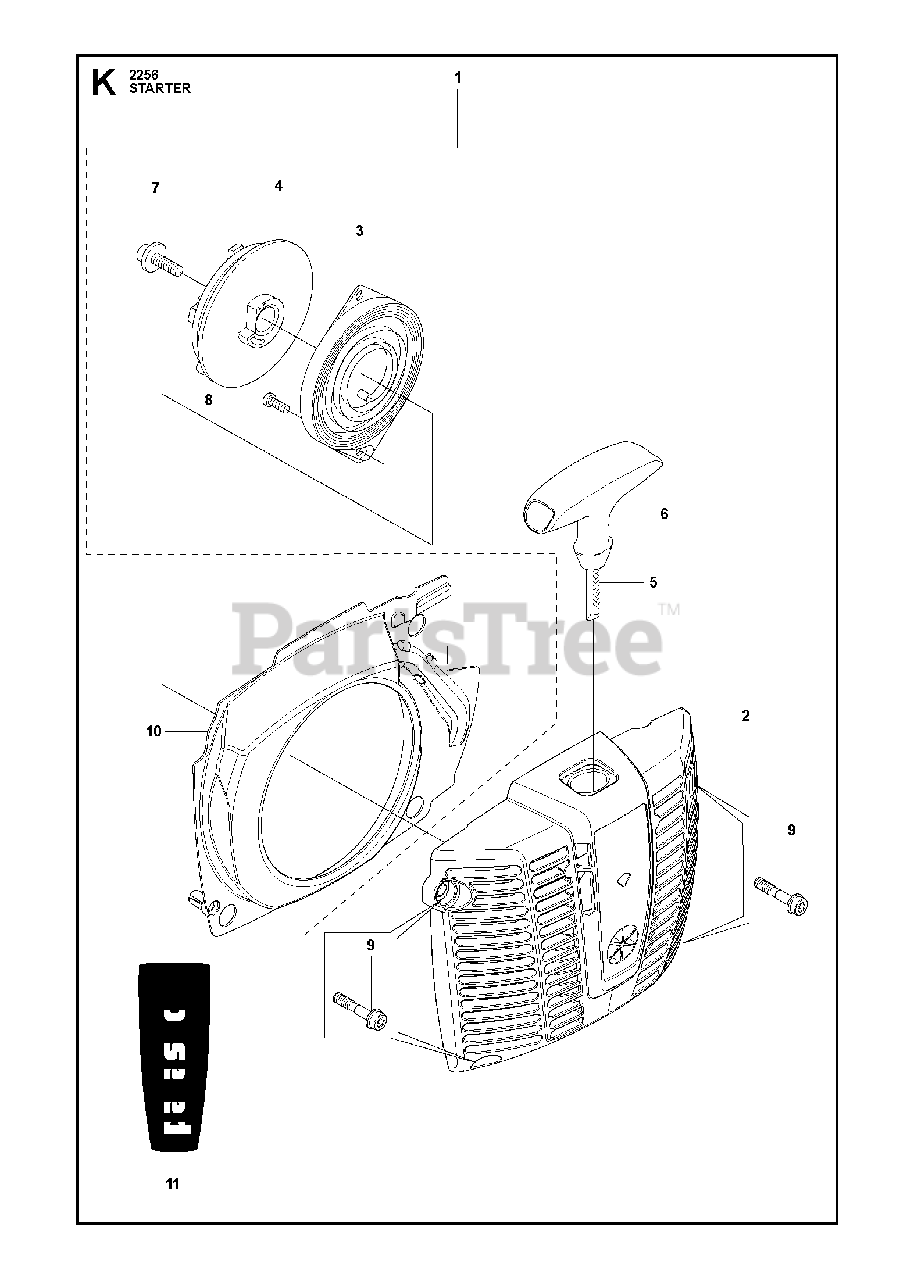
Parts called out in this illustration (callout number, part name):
3	RECOIL SPRING
4	STARTER PULLEY
5	STARTER ROPE
6	STARTER HANDLE
7	SCREW
8	SCREW
9	SCREW IHSCFMO
